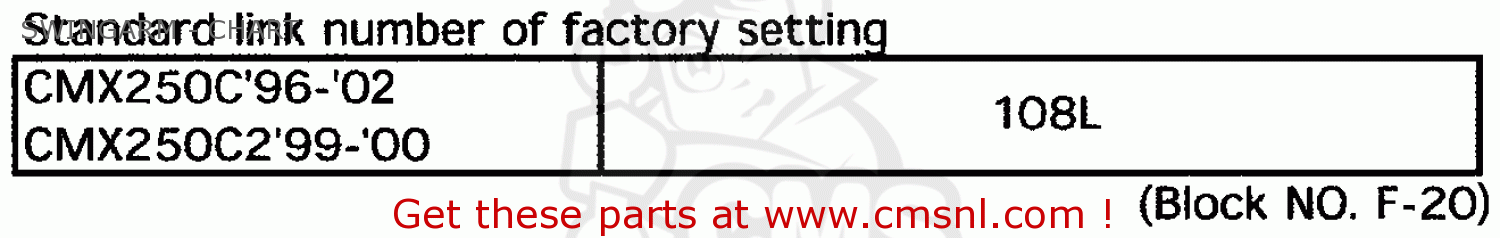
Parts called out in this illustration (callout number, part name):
1	CHAIN SET,DRIVE (
2	CASE,DRIVE CHAIN
3	SLIDER,CHAIN CASE
4	ADJUSTER,CHAIN
5	JOINT SET
6	CAP,REAR FORK END
7	ARM,RR.BRAK*NH-1*
8	BUSH,REAR FORK
9	COLLAR,RR.FORK,R
10	CAP,DUST SEAL
11	SLIDER,DRIVE CHAI
12	SET,SWINGARM*NH1*
13	BOLT,RR.FORK PIVO
14	NUT,SPECIAL,6MM
15	NUT,FLA/CAP 5MM
16	NUT,U,14MM
17	WASHER,6.5X18
18	WASHER,CHAIN SLID
19	BOLT A,ARM STOPP
20	SCREW,TAPPING,5X8
21	NUT,HEX 6MM
23	WASHER PLAIN 6MM
24	WASHER,PLAIN,8MM
25	SPG-WASHER 10MM
26	PIN,COTTER 2.0X15
27	BOLT,FLANGE,6X8
